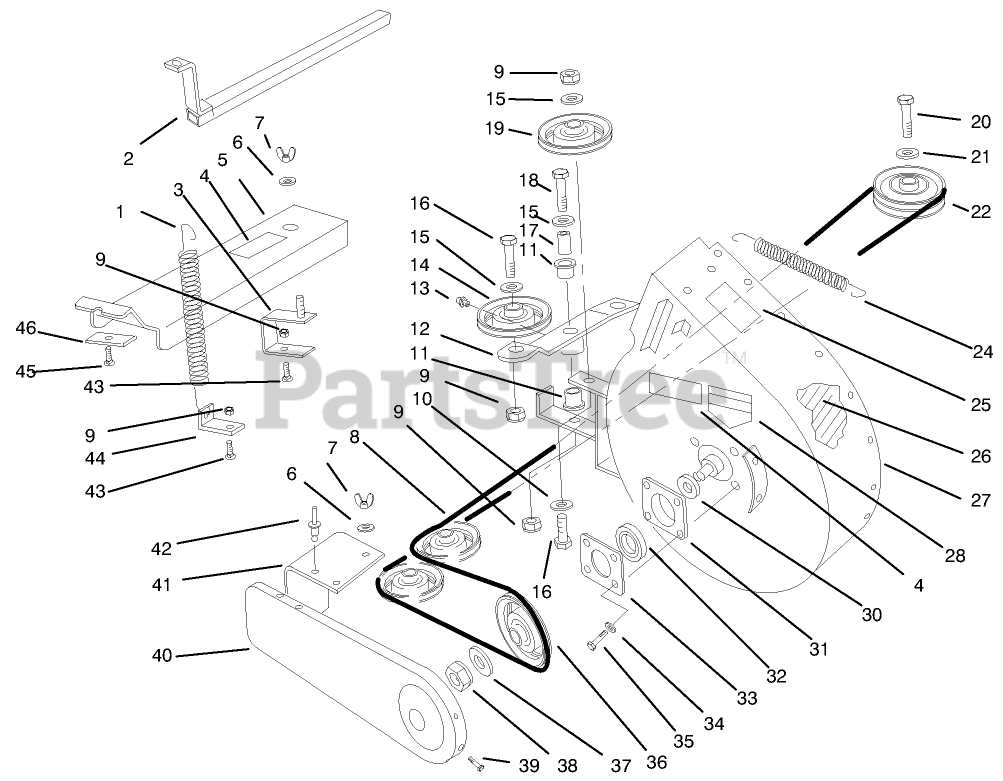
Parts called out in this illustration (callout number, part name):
1	SPRING-EXTENSION
2	SUPPORT-WELDED B
3	Bracket
4	DECAL-DANGER
5	Belt Cover Asm (Incl. Ref. #3)
6	WASHER-PLAIN
7	NUT-WING, LOCK
8	V-BELT
9	NUT-LOCK, NI
10	WASHER-FLAT
11	BUSHING
12	ARM-IDLER-WELDED B
13	FITTING-GREASE
16	SCREW-HH
17	SPACER
18	SCREW-HH
19	PULLEY-IDLER
20	SCREW-HH
21	Washer (Ref.)
22	PULLEY
24	SPRING - EXTENSION
25	DECAL-DANGER
